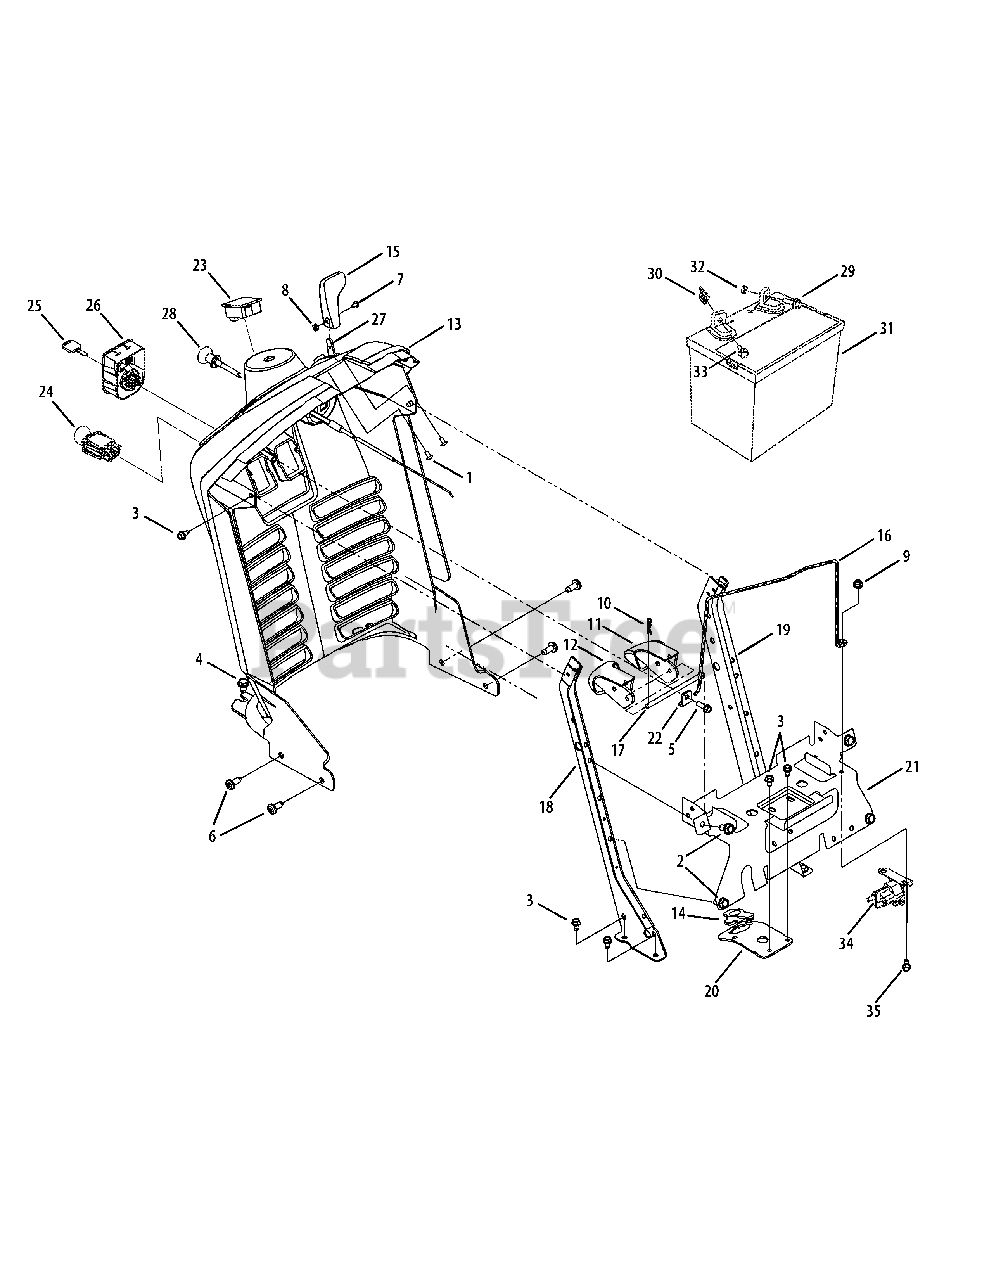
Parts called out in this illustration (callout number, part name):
1	Screw, #10-24 x .375
2	Screw, Hex, 5/16-18 x .750
3	Screw, Self-tapping, 1/4-20, 0.500
4	Screw, Hex, 5/16-18 x .500
5	Screw, 1/4-15, 0.750
6	Screw, Torx Hd. Tapp. 5/16-18 x .75
7	Screw, Machine, #8-32, 0.375
8	Nut, 8-32
9	Nut, Nylon Lock, 1/4-20
10	Internal Cotter Pin, .072 x 1.13
11	Lever, Dash, Brake
12	Lever, Dash, Cruise
13	Dash
14	Steering Colume Bearing
15	Knob, Throttle Control
17	Rod, .250 Dia x 4.25 Lg.
23	Monitor, Sys. Indicator / Hour Meter
24	Switch, PTO, Yellow
25	Ignition Key, Plastic
26	Switch Module, Ignition
27	Throttle, 27.4
27	Throttle, 38.0
28	Choke, 24.0
28	Choke, 37.5
29	Shoulder Screw, .250 x .150, 1/4-20
30	Wing Nut, 1/4-20
31	Battery, 190 CCA
31	Battery, 235 CCA
32	Nut, Sems, 1/4-20
33	Screw, Flange, 1/4-20, .75,
34	Solenoid, 12V, 100 Amp
35	Screw, 1/4-20, .750
